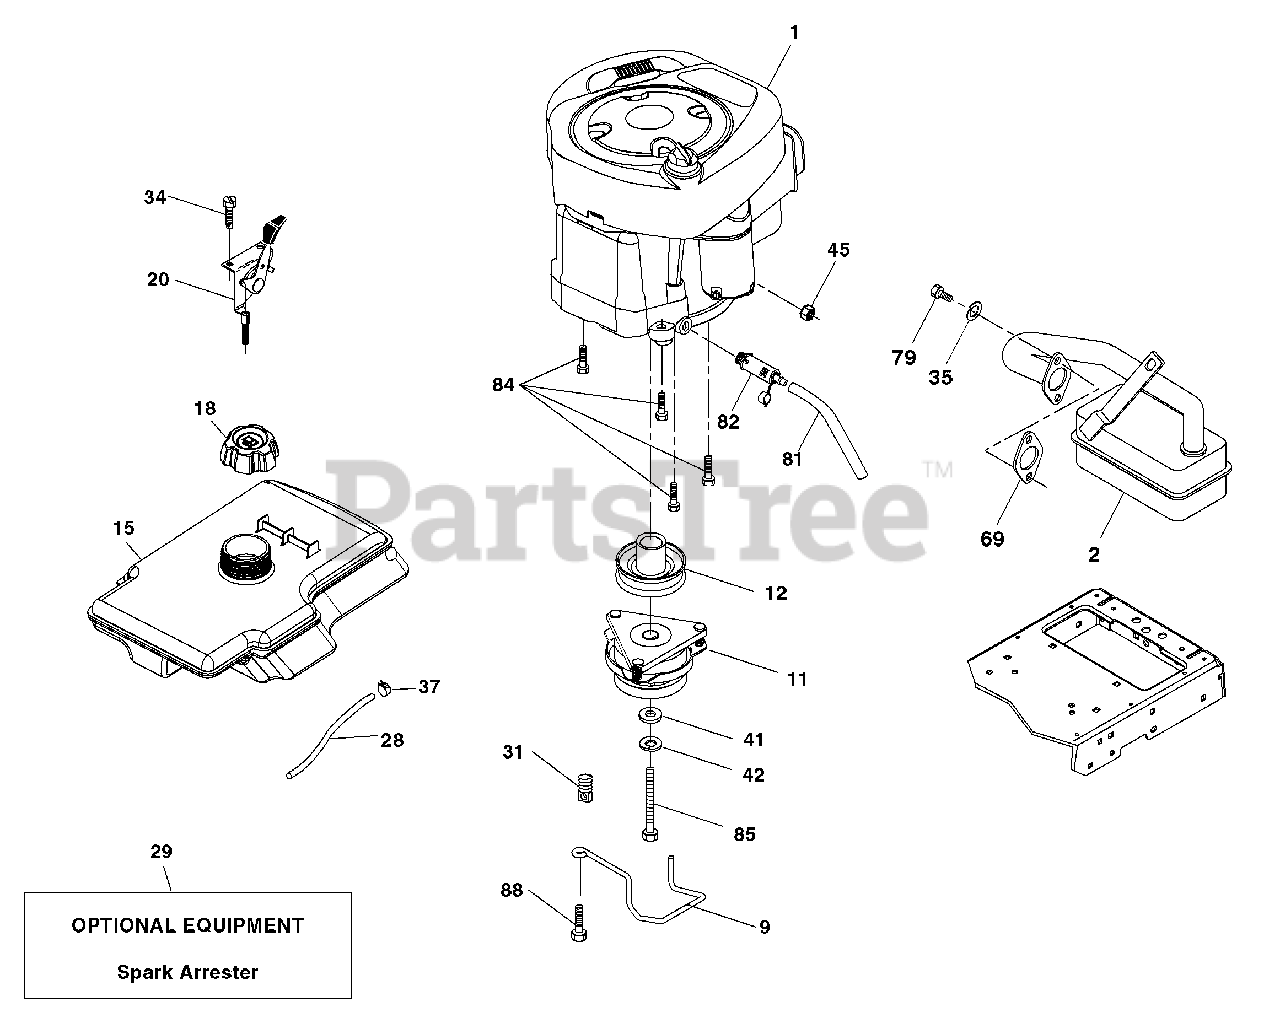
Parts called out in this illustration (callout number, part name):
9	Keeper Belt Engine
11	Clutch Ogura
12	Pulley Engine
15	Tank Fuel
18	Cap Asm
20	Control Throttle
28	Fuel Line
29	Spark Arrester Kit
31	Clip Push-In Hinged
34	Screw thd Cut 1/4-20 x 1/2
35	Washer Split
37	Clamp Hose
41	Washer 1-1/2 OD x 15/32 ID x .250
42	Washer Lock 7/16
45	Nut Keps Hex 1/4-20 unc
69	Gasket
79	Screw Socket Head 5/16-18 x .75
81	Tube Drain Oil Easy
82	Plug Drain Oil
84	Screw 3/8-16 x 1-1/4
85	Bolt Hex 7/16-20 x 4 x Gr. 5-1.5 Thr
88	Screw 3/8-16 x 1
